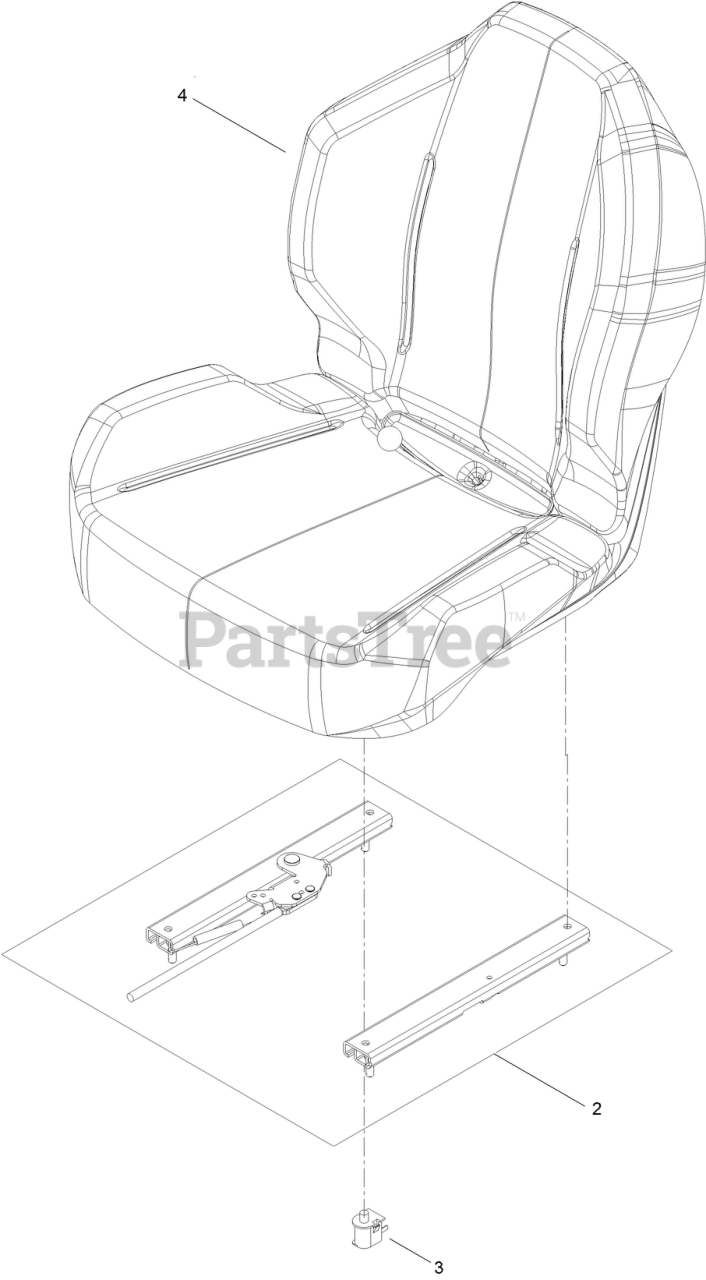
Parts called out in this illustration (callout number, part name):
2	KIT-ADJUSTER
3	SWITCH-BAIL
4	COVER-SEAT
